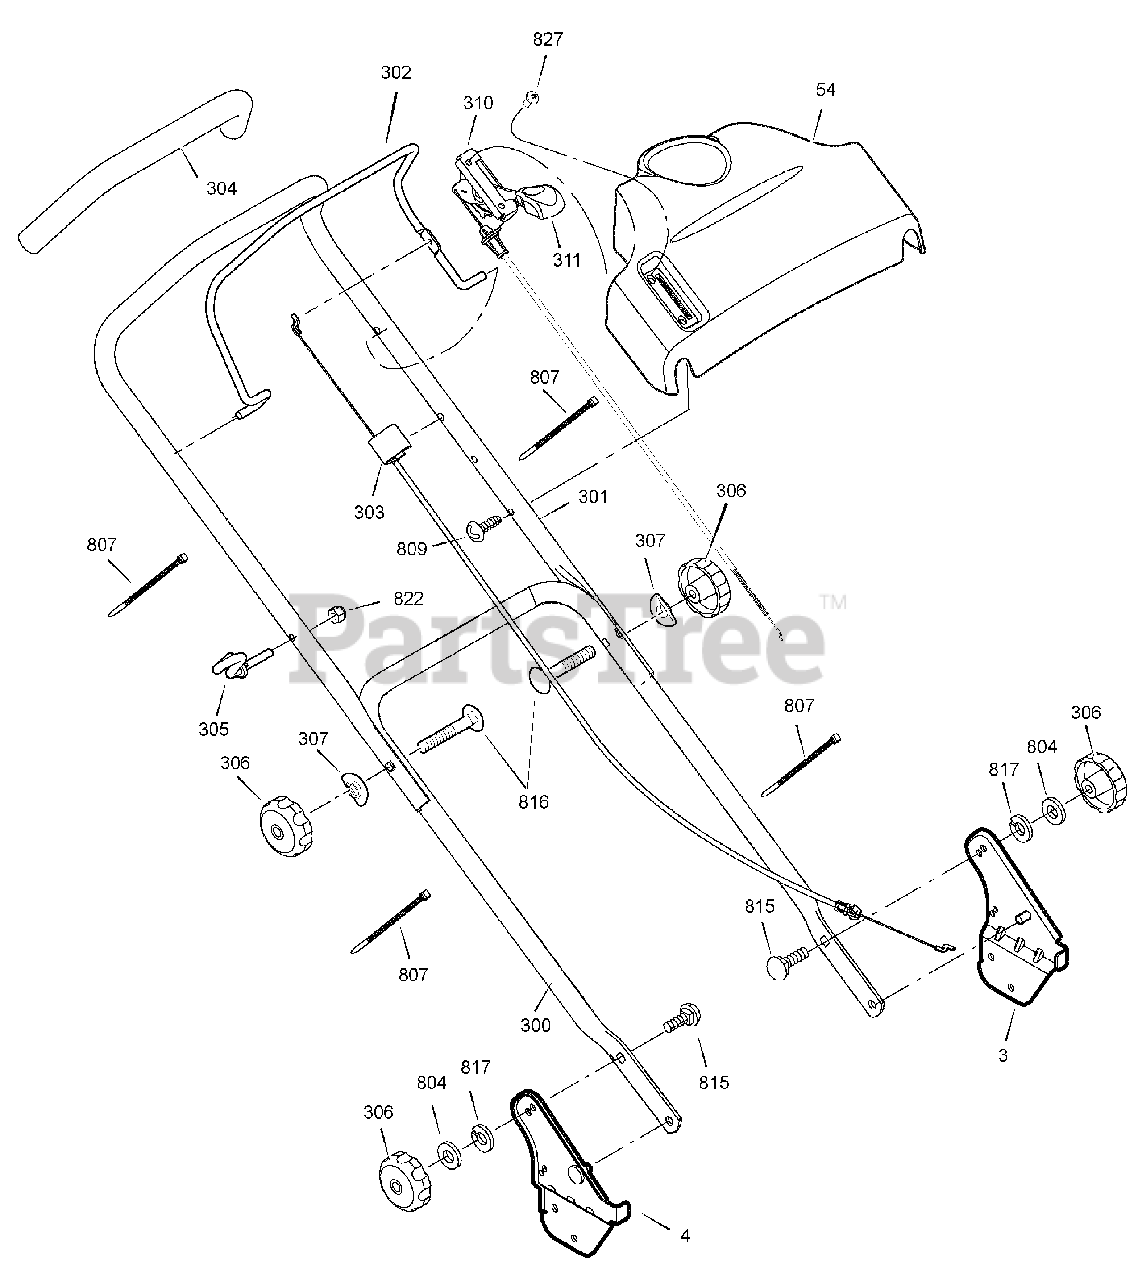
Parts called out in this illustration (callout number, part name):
3	BRACKET ASSEMBLY, Left Handle
4	BRACKET ASSEMBLY, Right Handle
54	CONTROL PANEL
300	HANDLE, Lower
301	HANDLE, Upper
302	LEVER, Engine Stop
303	CABLE, Engine Stop
304	TUBING, Foam
305	GUIDE, Rope
306	KNOB, Adjuster
307	WASHER, Formed
310	THROTTLE CONTROL
311	KNOB, Throttle Control
804	WASHER, 5/8
807	CABLE TIE
809	SCREW, Self Tap, #10-16 x 1/2
815	BOLT, Carriage, 5/16-18 x 1-1/8
816	BOLT, Carriage, 5/16-18 x 2
817	Washer, Lock
822	NUT, Hex, 1/4-20
827	SCREW, 1/4-20 x 7/8
